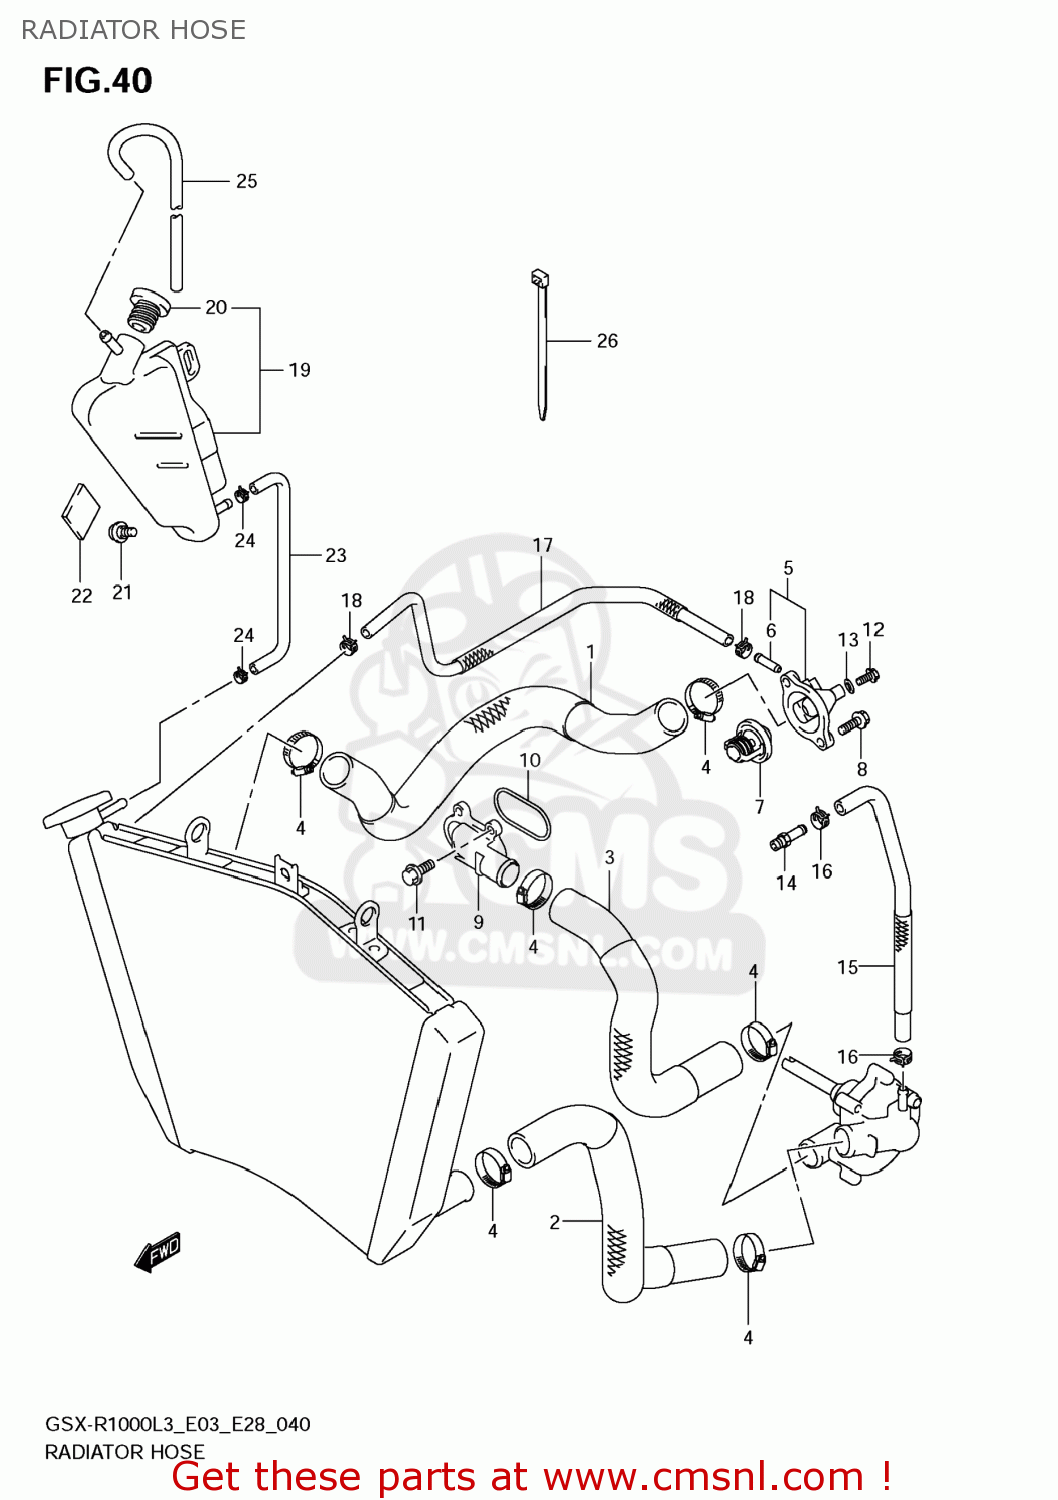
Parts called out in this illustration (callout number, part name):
1	HOSE,RADIATOR INLET
2	HOSE,RADIATOR OUTLET
3	HOSE,CYLINDER INLET
4	CLAMP
5	COVER,THERMOSTAT
6	UNION
7	THERMOSTAT,WATER
8	BOLT
9	CONNECTOR,CYLINDER WATER INLET
10	O RING,CYL WATER CONNECTOR
11	BOLT
12	UNION BOLT,AIR VENT
13	GASKET(6.4X11.5X0.8) (NAS)
14	BOLT UNION
15	HOSE,WATER BYPASS
16	CLAMP
17	HOSE,WATER AIR BLEED
18	CLIP
19	TANK ASSY,RESERVOIR
20	CAP,RESERVOIR TANK
21	BOLT(6X12)
22	CUSHION
23	HOSE,RESERVOIR TANK INLET
24	CLIP
25	HOSE,RESERVOIR TANK OVFL
26	CLAMP(L:100)
